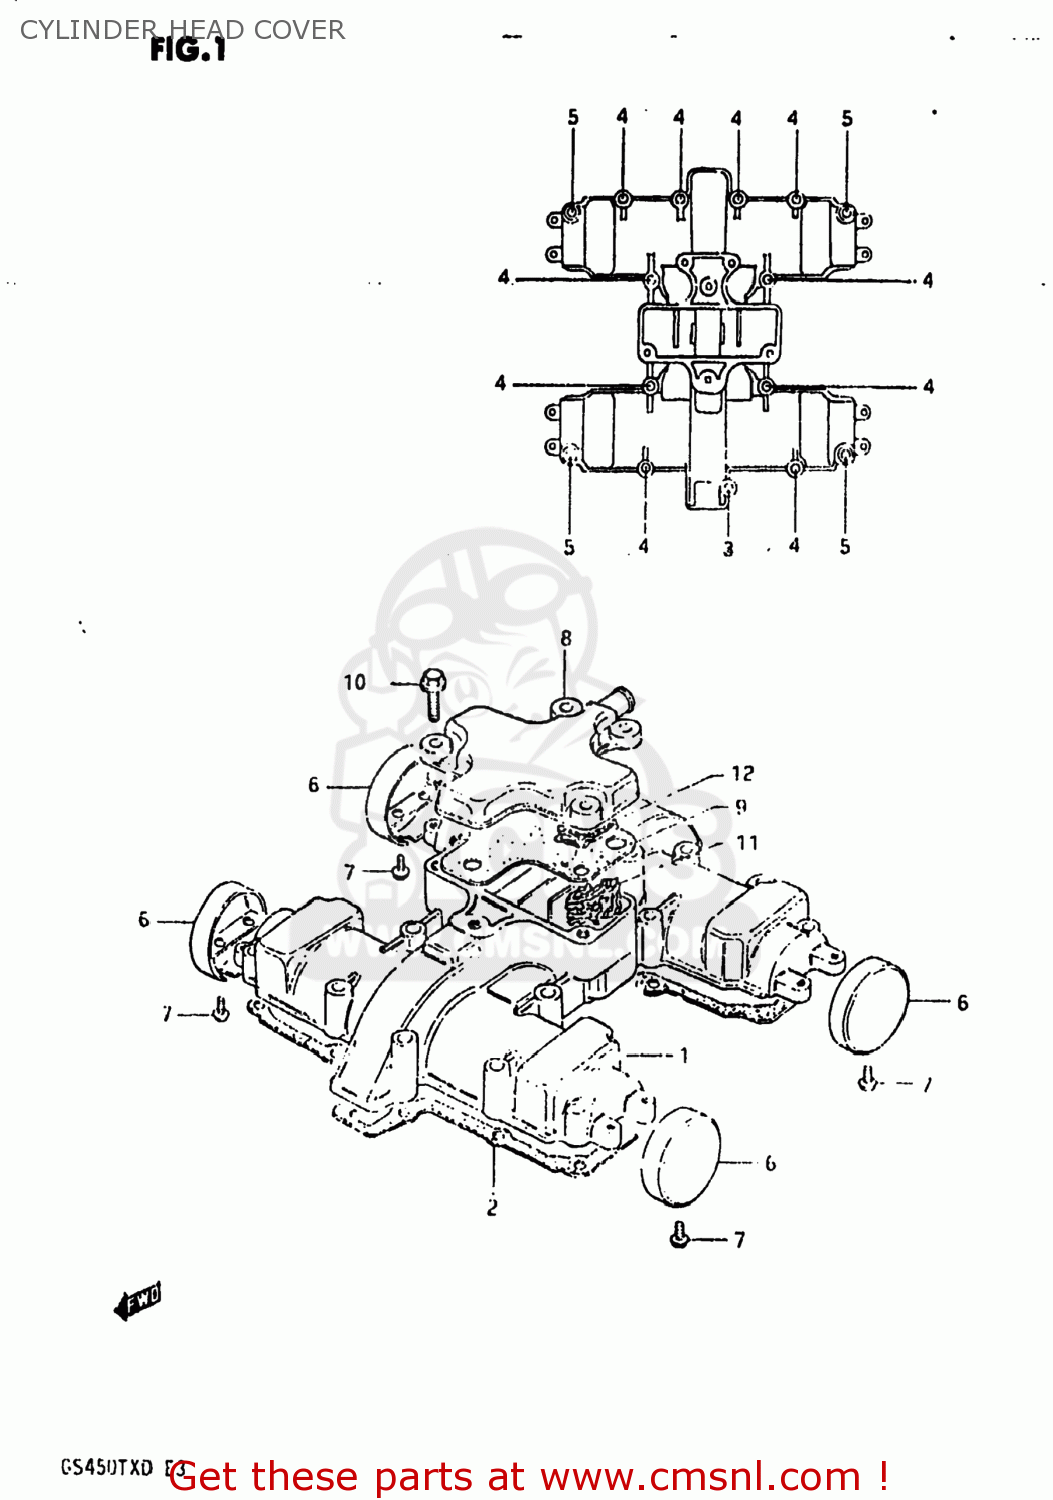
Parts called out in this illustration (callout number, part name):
1	COVER,CYLINDER HEAD
2	GASKET,CYLINDER HEAD COVER (MCA)
3	BOLT,UNDER
4	BOLT
5	BOLT
6	CAP,CYLINDER HEAD COVER
7	SCREW
8	COVER,BREATHER
9	GASKET (MCA)
10	BOLT,REAR
11	COVER,BREATHER
12	SEPARATOR,OIL BREATHER
